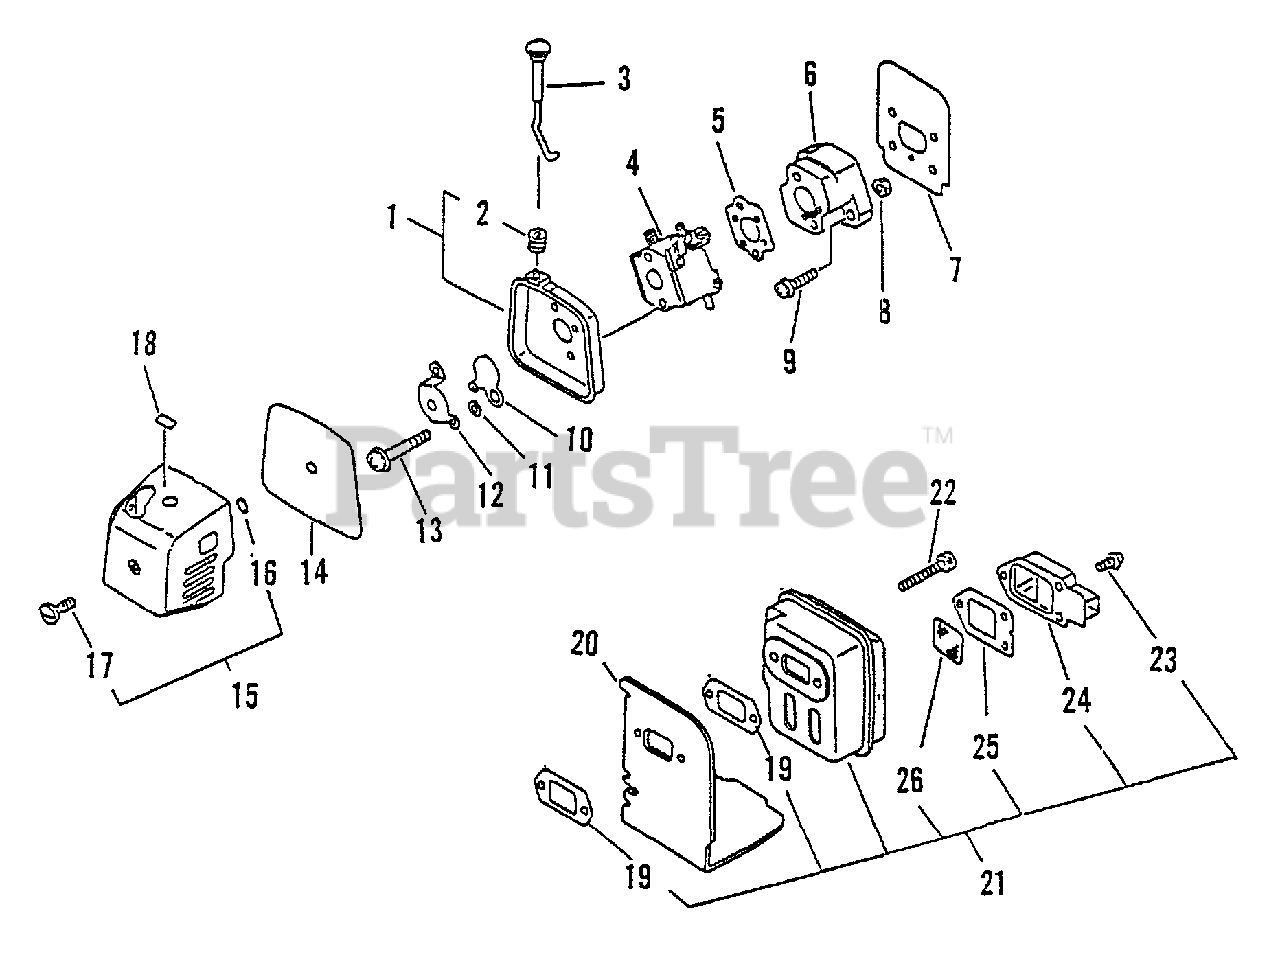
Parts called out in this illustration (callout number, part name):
1	CASE, AIR FILTER
2	GROMMET, CHOKE
3	ROD, CHOKE
4	CARBURETOR
5	GASKET, INTAKE
6	INSULATOR, INTAKE
7	HEAT SHIELD, INTAKE
8	NUT M5
9	SCREW 5×20
10	SHUTTER, CHOKE
11	WASHER 5.2×8×0.8T
12	CASE, AIR FILTER
13	SCREW 5×57
14	FILTER, AIR
15	COVER ASSY, AIR FILTER
18	LABEL, CHOKE
19	GASKET, EXHAUST
20	COVER, EXHAUST
21	MUFFLER ASSY
22	BOLT 5×55
22	WASHER, FLAT 5.5×10×0.8
23	SCREW 4×10
24	GUIDE, EXHAUST - INNER
25	GASKET, EXHAUST
26	SCREEN, SPARK ARRESTER
